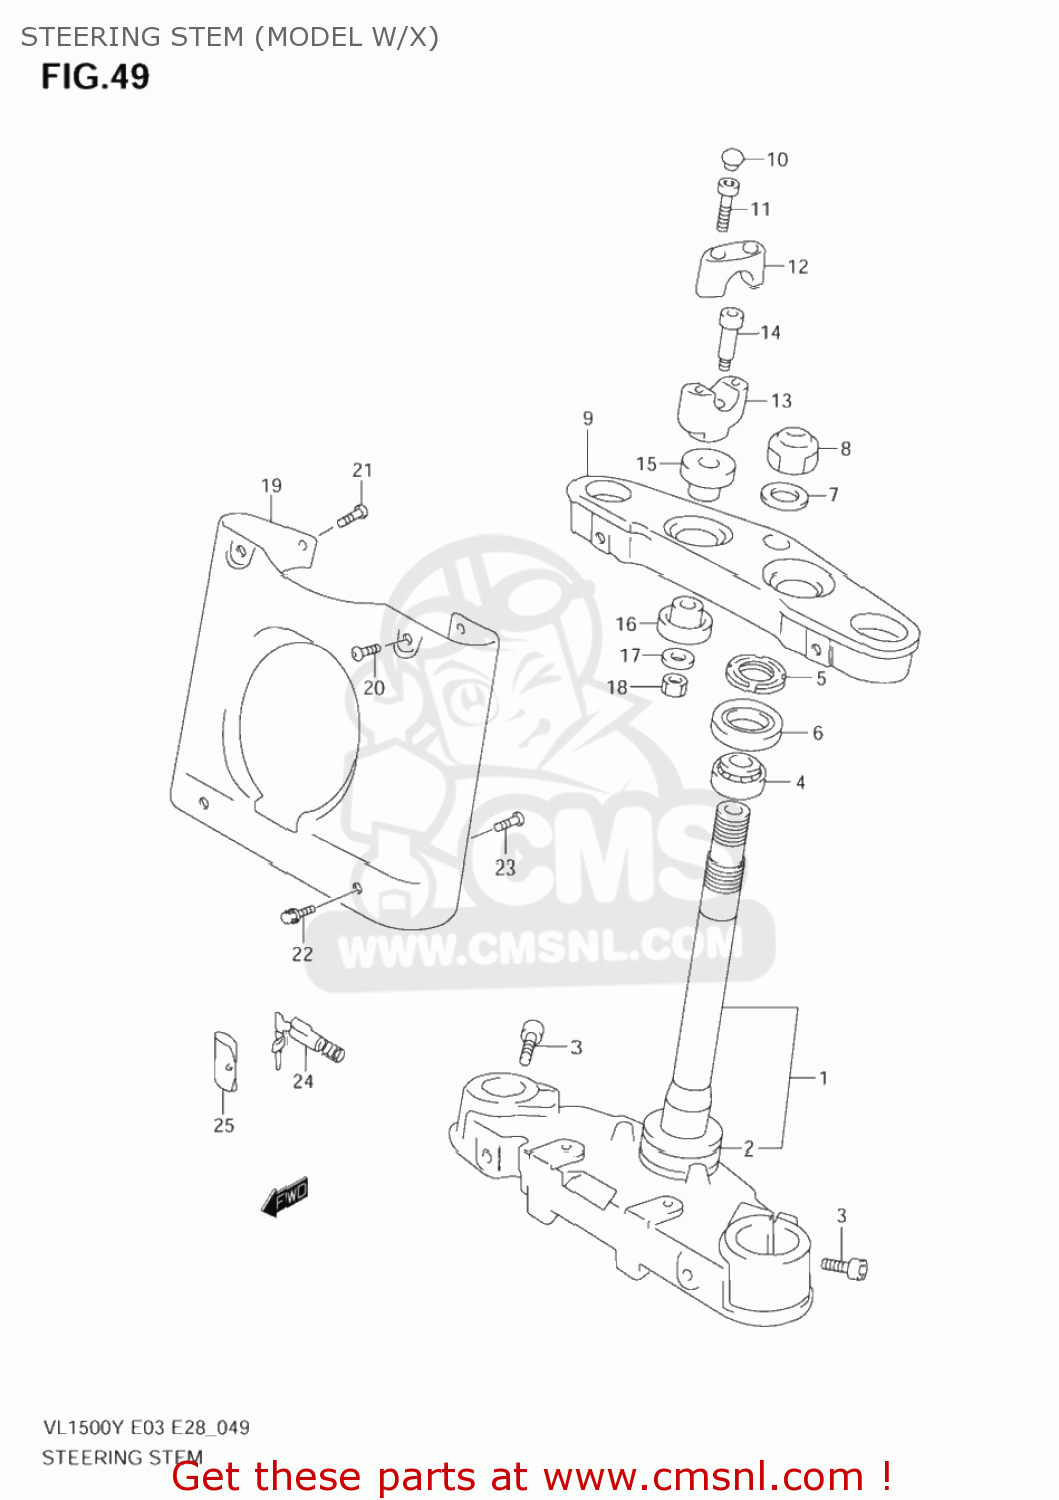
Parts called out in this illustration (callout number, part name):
1	STEM,STEERING
2	BEARING(30X55X17)
3	BOLT,STEM
4	BEARING(25X47X15)
5	NUT,STEERING STEM(25X44X10)
6	DUST SEAL,STEERING UPR
7	WASHER(22.5X32X1.6)
8	NUT,CAP
9	HEAD,STEERING STEM
10	CAP(OD:14.5)
11	BOLT
12	HOLDER,HANDLE UPR
13	HOLDER,HANDLE UNDER
14	BOLT
15	DAMPER,RUBBER
16	CUSHION,RUBBER UNDER
17	WASHER
18	NUT
19	COVER,FR FORK UPR
20	SCREW(8X16)
21	SCREW(6X12)
22	BOLT
23	SCREW(6X12)
24	LOCK SET,STEERING
25	CASE,STEERING KEY
